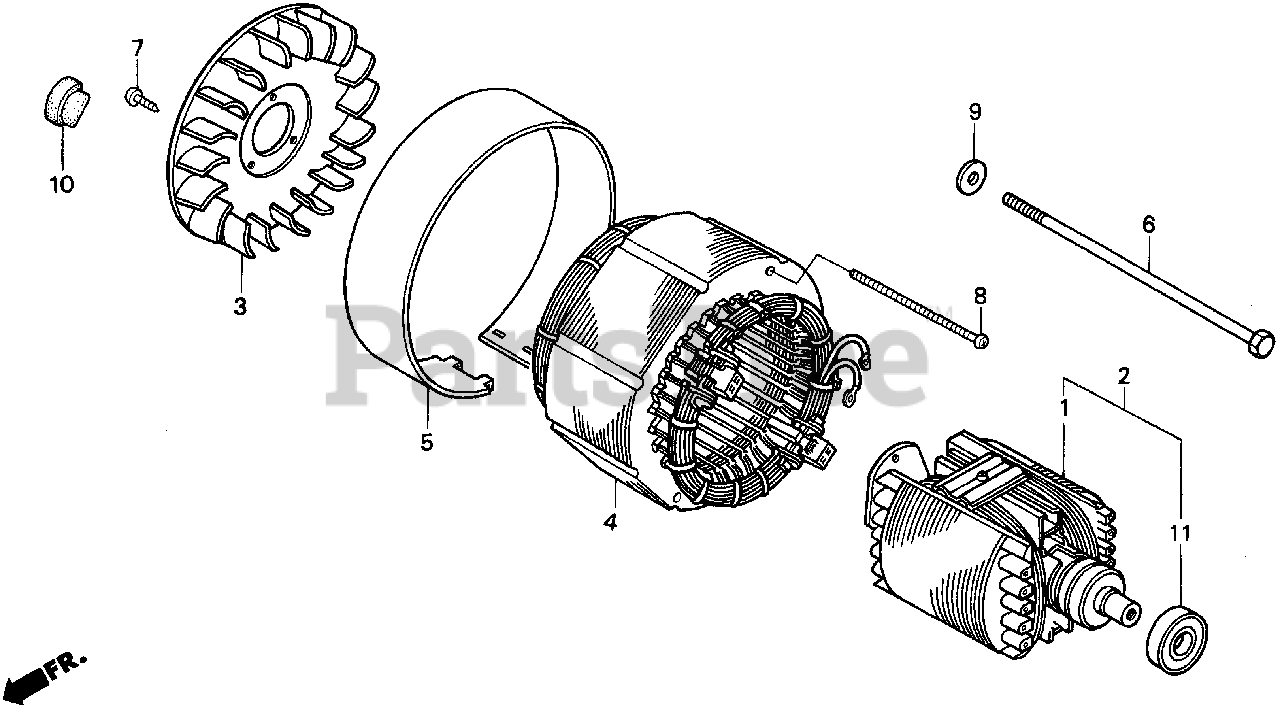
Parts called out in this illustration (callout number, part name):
1	ROTOR
2	ROTOR
3	FAN, GENERATOR COOLING
4	STATOR ASSY.
5	COVER, STATOR
6	BOLT, HEX. (10X210)
7	SCREW, TAPPING (5X14)
8	BOLT-WASHER (5X155)
9	WASHER (10.5MM)
10	GROMMET, CRANKCASE
11	BEARING ASSY. (6204)
11	BEARING, RADIAL BALL (6204UU)
